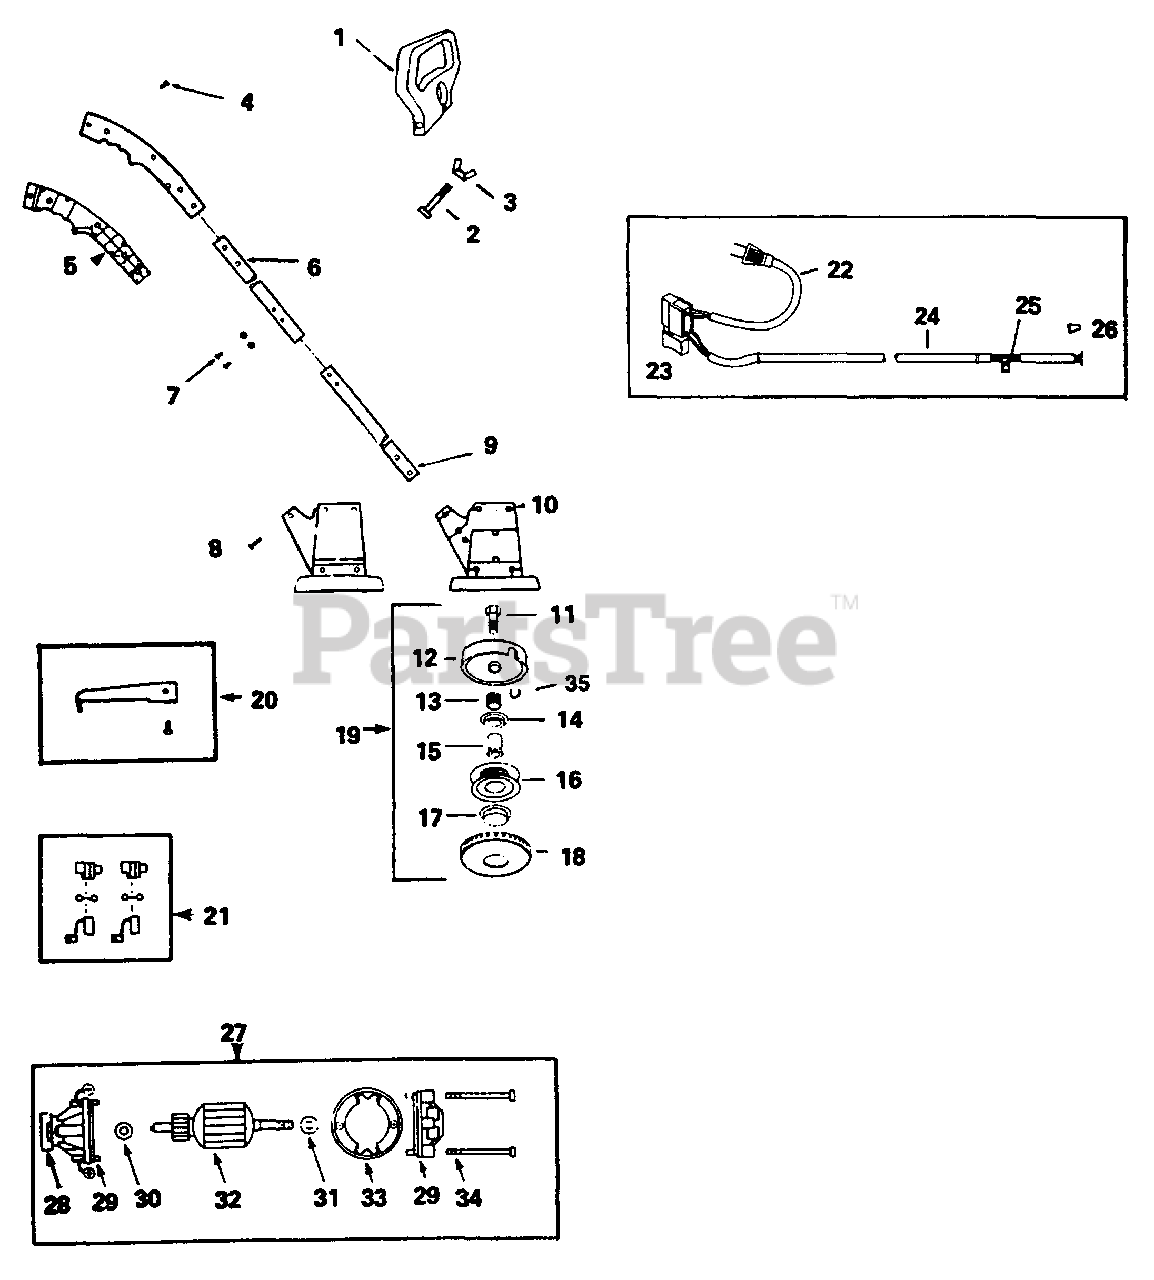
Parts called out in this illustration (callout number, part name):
1	ASSIST HANDLE
3	WING NUT
4	SCREW
5	TRIGGER HANDLE SET
6	TUBE, UPPER
7	TUBE FASTENER KIT
8	SCREW
9	TUBE, LOWER
10	MOTOR HOUSING SET
11	DRIVE ADAPTOR
12	HUB w/LINE SAVER
13	SPRING
14	SPRING ADAPTOR
15	DRIVE GEAR
16	SPOOL, WOUND
17	RELEASE BUTTON
18	COVER
19	TAP-N-GO HEAD ASSEMBLY
20	LINE LIMITER KIT
21	BRUSH KIT
22	POWER CORD PIGTAIL
23	SWITCH
24	HARNESS w/DIODE
25	DIODE
26	CONNECTOR
27	MOTOR
28	INSULATOR
29	END BELL SET
30	WASHER-THRUST, .025"
31	WASHER-THRUST, .010"
32	ARMATURE
33	FIELD ASSEMBLY
34	SCREW
35	LINE SAVER
